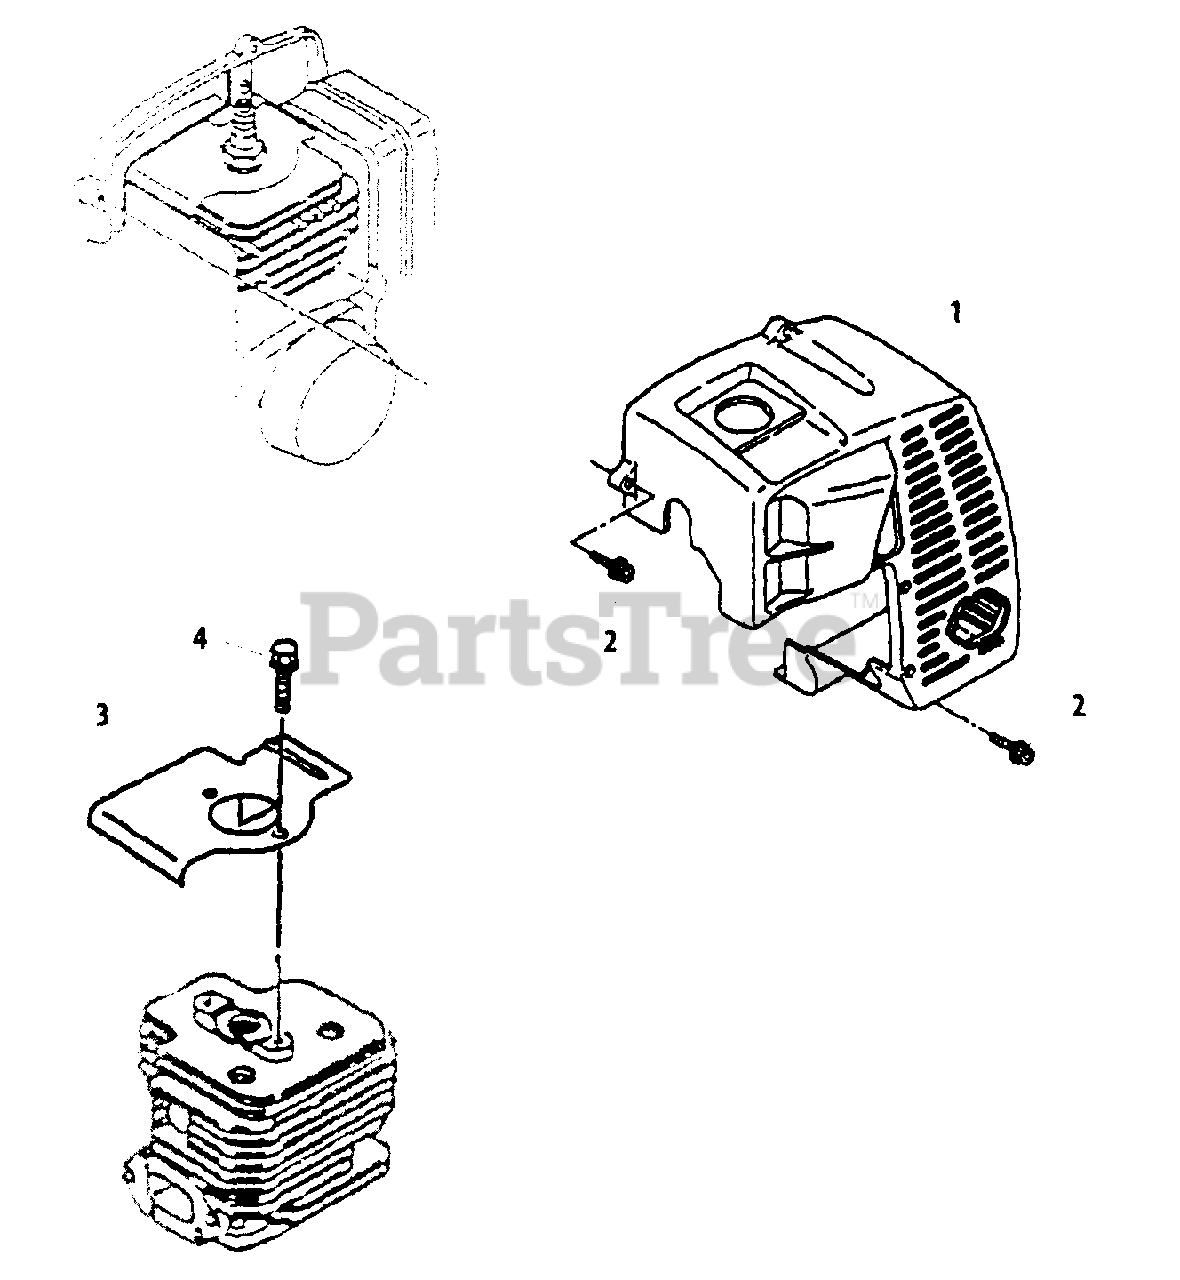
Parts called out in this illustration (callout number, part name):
1	COVER, ENGINE
2	BOLT - 5X20
3	SHIELD, CYLINDER
